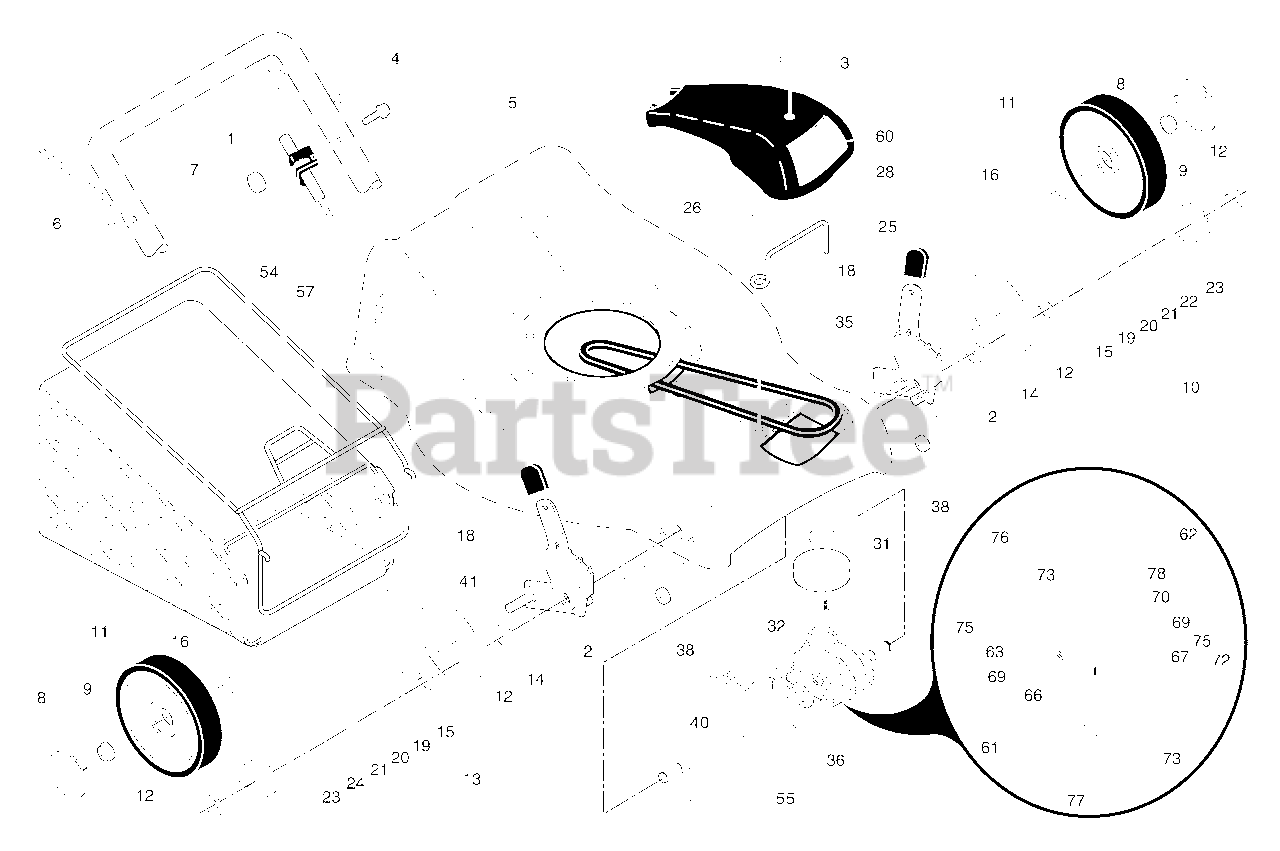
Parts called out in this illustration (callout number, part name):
1	Drive Control Assembly, with Cable
2	Bearing, Wheel Adjuster
3	Pan Head Tapping Screw #10-24 x 2-3/4
4	Hex Washer Head Screw 1/4-20 x 2.12
6	Control Bar, Drive
7	Locknut #10-24
8	Hubcap
9	Locknut
10	Pinion Assembly, LH
11	Wheel & Tire Assembly
13	Pinion Assembly, RH
14	Dust Cover
15	Seal, Friction
16	Washer 1/2 x 1-1/2 x .134
18	Selector Knob
19	Disk, Drive
20	Spring, Torsion
22	Retainer, Drive, LH
23	Gear, Pinion
24	Retainer, Drive, RH
25	Belt Keeper
28	Drive Cover
31	Hex Flange Nut
32	Drive Pulley
35	Kit, Wheel Adjuster, LH
36	Gearcase Assembly, Complete
38	Locknut 1/4-20
40	Spring
41	Kit, Wheel Adjuster, RH
54	Grassbag Assembly
55	Driveshaft Cover
57	Frame, Grassbag
60	Decal, Drive Cover
61	Case, Lower
62	Case, Upper
63	Gear, 27 Teeth
66	Shaft, Input
69	Wire, Formed
70	Bearing, Ball
72	Seal, Output Shaft
76	Shaft, Output
78	Seal, Input Shaft
